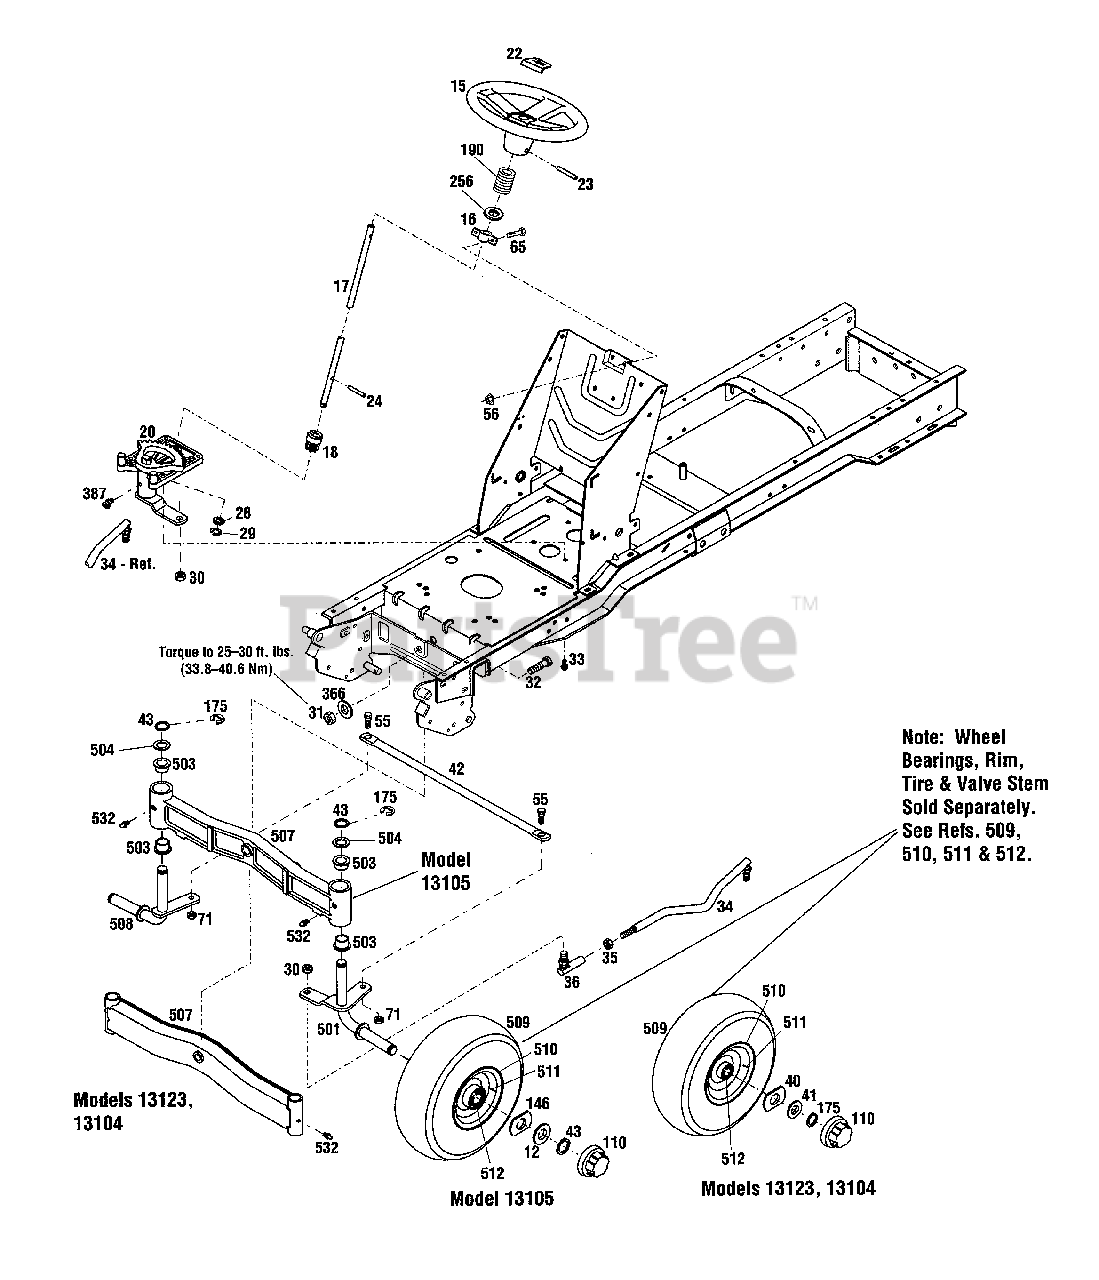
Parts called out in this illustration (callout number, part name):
15	Premium Steering Wheel
16	Steering Support Bearing
17	Steering Shaft
18	Pinion Gear
20	Steering Gear Assembly
22	Steering Wheel Cap
23	Roll Pin, 1/4 x 2
24	Drive Pin, 1/4 x 1 1/4
28	Special Washer, 5/8 x 1
29	Retaining Ring, 5/8
30	Locking Jam Nut, 1/2-20
31	Top Locknut, 5/8-11
32	Hex Head Screw, 5/8-11 x 2 3/4
33	Flange Lock Screw, 5/16-18 x 3/4
34	Drag Link
35	Hex Jam Nut, 1/4-20
36	Ball Joint
40	Special Washer, 3/4 x 2 1/2
41	Special Washer, 3/4 x 1-3/8
43	Retaining Ring
55	Shoulder Bolt, 3/4-24
56	Flange Nut, 1/4-20
65	Flange Screw, 1/4-20 x 5/8
71	Self Lock Nut, 3/4-24
110	Hub Cap
146	Special Washer, 1 x 2-1/2
175	Retaining Ring
190	Compression Spring
256	Flat Washer, 5/8 x 1"
366	Flat Washer, 5/8
387	90° Grease Fitting
501	Left-Hand Spindle
503	Axle Bushing,
504	Special Washer, 3/4
507	Front Axle
508	Right-Hand Spindle
509	Tire, 15 x 6.00 BRS
510	15" Rim Assembly
511	Valve Stem
512	Wheel Bearings
532	Grease Fitting
